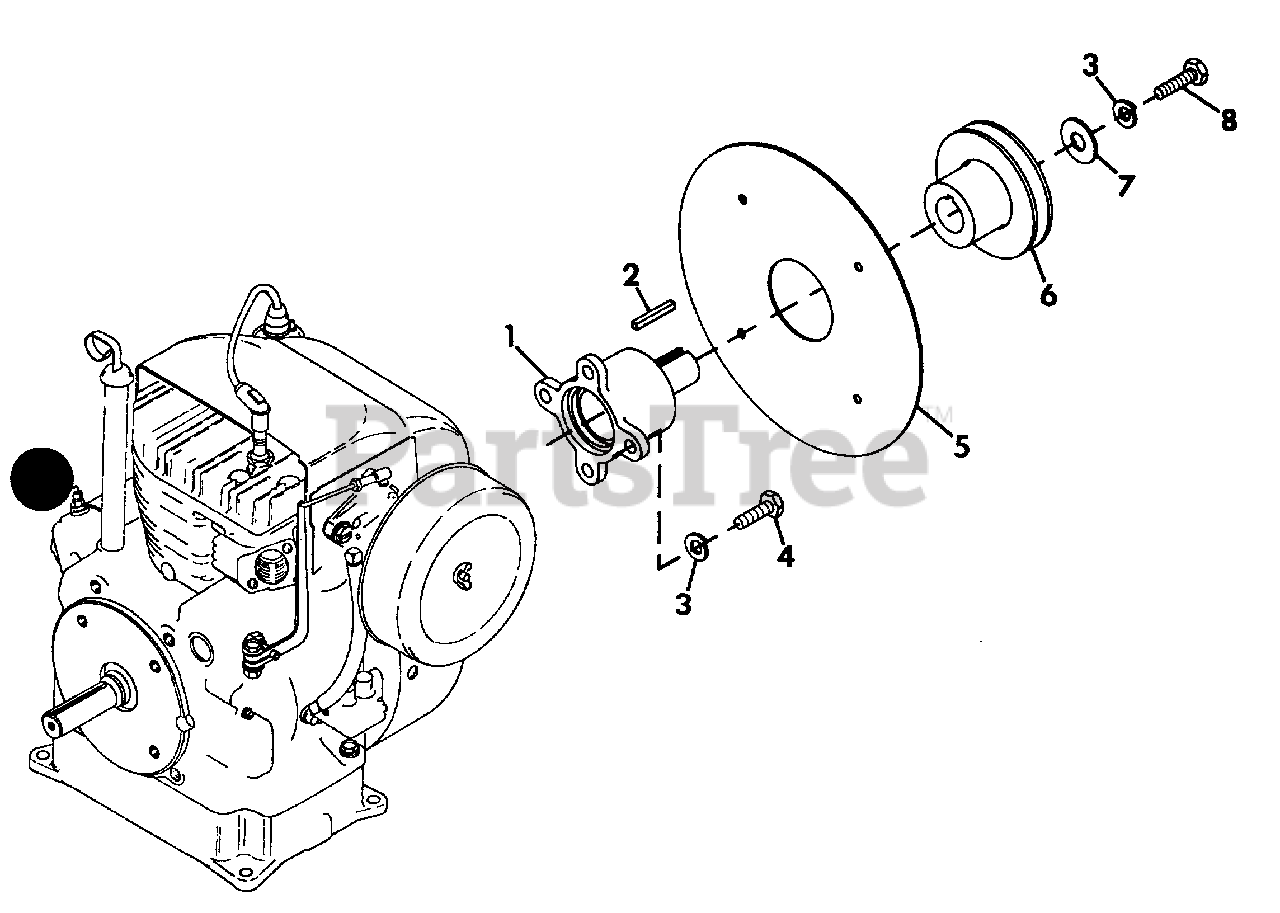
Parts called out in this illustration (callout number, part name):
1	ADAPTOR, DRIVE KOHLER
2	KEY, SQUARE .250X2.00
3	WASHER, LOCK 3/8
4	BOLT, HEX 3/8-16X1.00
5	SCREEN, GRASS KOHLER
6	SHEAVE, ENGINE
7	WASHER, FLAT 1.25X.50 HARD
8	BOLT, HEX 3/8-16X2.00
